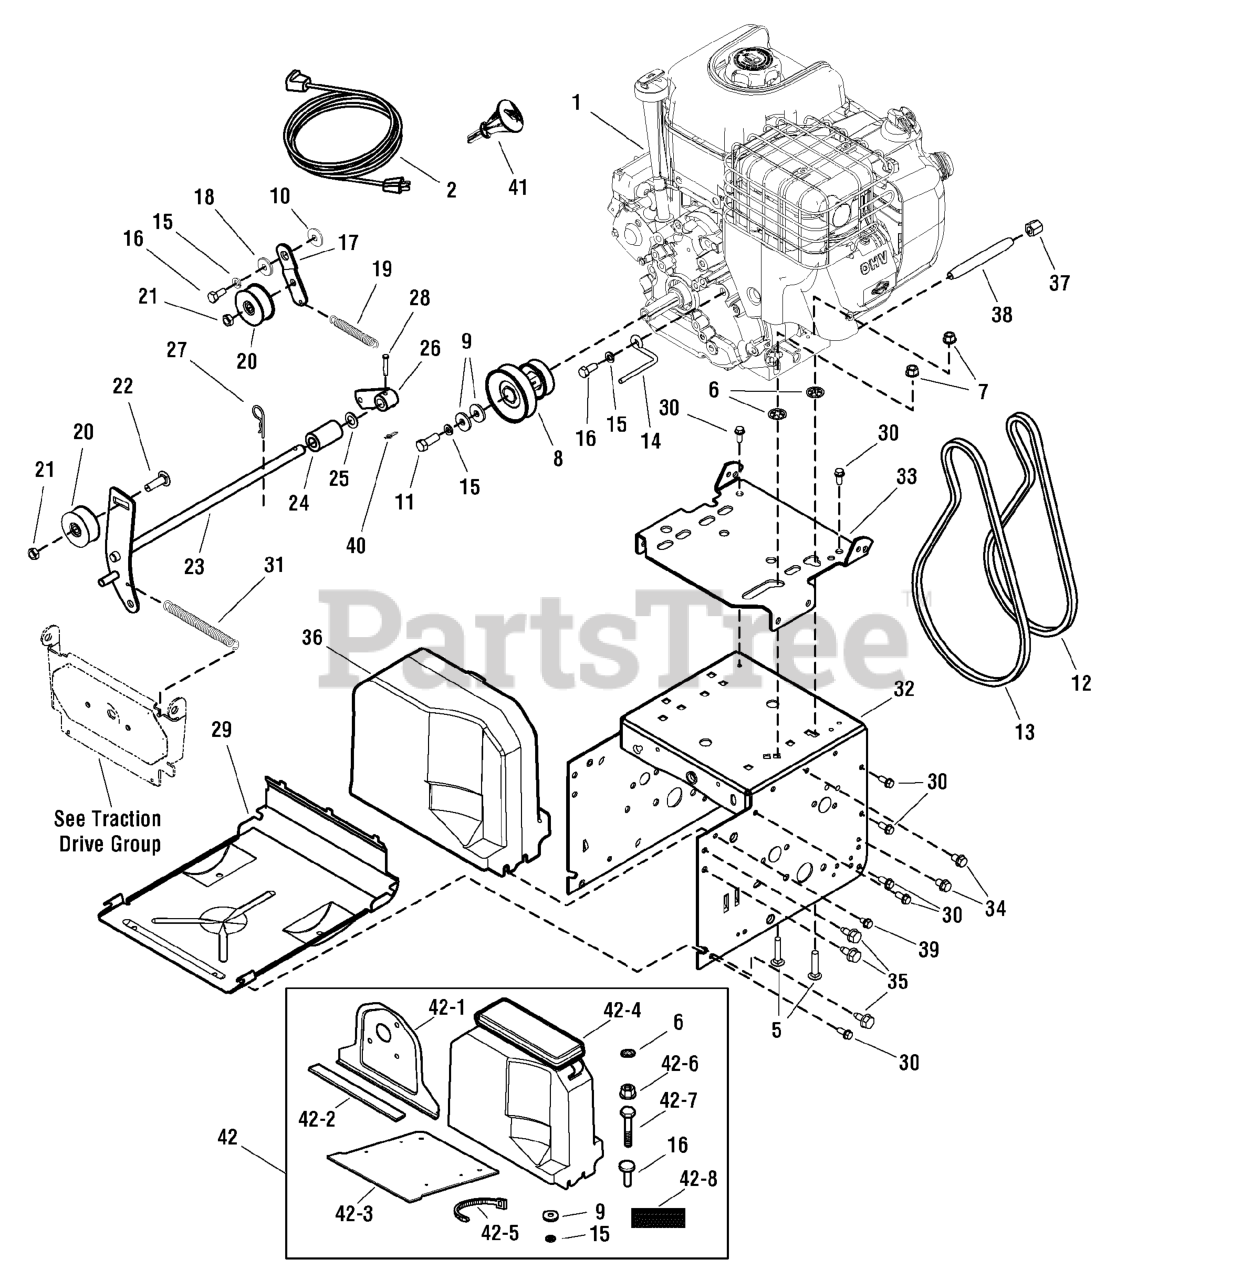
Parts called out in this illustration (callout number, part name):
2	CORD, Electric, 10FT. 110V
5	BOLT, Carriage, 5/16-18 x 1-1/2
6	NUT, Speed, 1/4
7	NUT-HEX FLANGE.312-18 ESNA
8	PULLEY, Engine
9	WASHER, 5/16
10	WASHER, Locking, 3/8
11	CAPSCREW, Hex-Head, 3/8-24 x 1-1/4
12	V-BELT, Drive, 3L
13	V-Belt, Auger, 4L
14	GUIDE, Belt
15	WASHER, Locking, 5/16
16	BOLT, Hex-Head, 5/16-24 x 3/4
17	ASSEMBLY, Idler Bracket
18	BUSHING, Idler Bracket
19	SPRING, Extension
20	IDLER, Plastic, Ball Bearing
21	NUT, Hex-Jam, 3/8-16
22	BOLT, Carriage, 3/8-16 x 1-1/4
23	IDLER ASSEMBLY, Auger
24	SPACER, 1/2ID x 1OD x 1-3/4
25	WASHER, Flat, 1/2
26	ASSEMBLY, Spring Attachment
27	PIN, Hair
28	PIN, Clevis
29	PANEL, Bottom
30	SCREW, 1/4-20 x 5/8
31	SPRING, Extension
32	FRAME, Steerable
33	ENGINE MOUNT
34	SCREW, 3/8-18 x 1/2
35	SCREW, 3/8-18 x 3/4
36	COVER, Belt
37	CAP, Pipe
38	PIPE, Oil Drain
39	SCREW, Hex-Washer, 1/4 x 3/4, Self-Tapping
40	PIN, Cotter, 1/4, Self-Locking
41	KEY, Ignition
42	KIT, Drive Seal
42-1	SEAL PLATE
42-2	SEAL STRIP
42-3	SEAL, Engine Plate
42-4	BELT COVER
42-5	TIE, Self Locking
42-6	NUT, Hex Flange Two-Way Lock, 5/16-18
42-7	SCREW, 5/16-24 x 1.00
42-8	DECAL, Hinge
